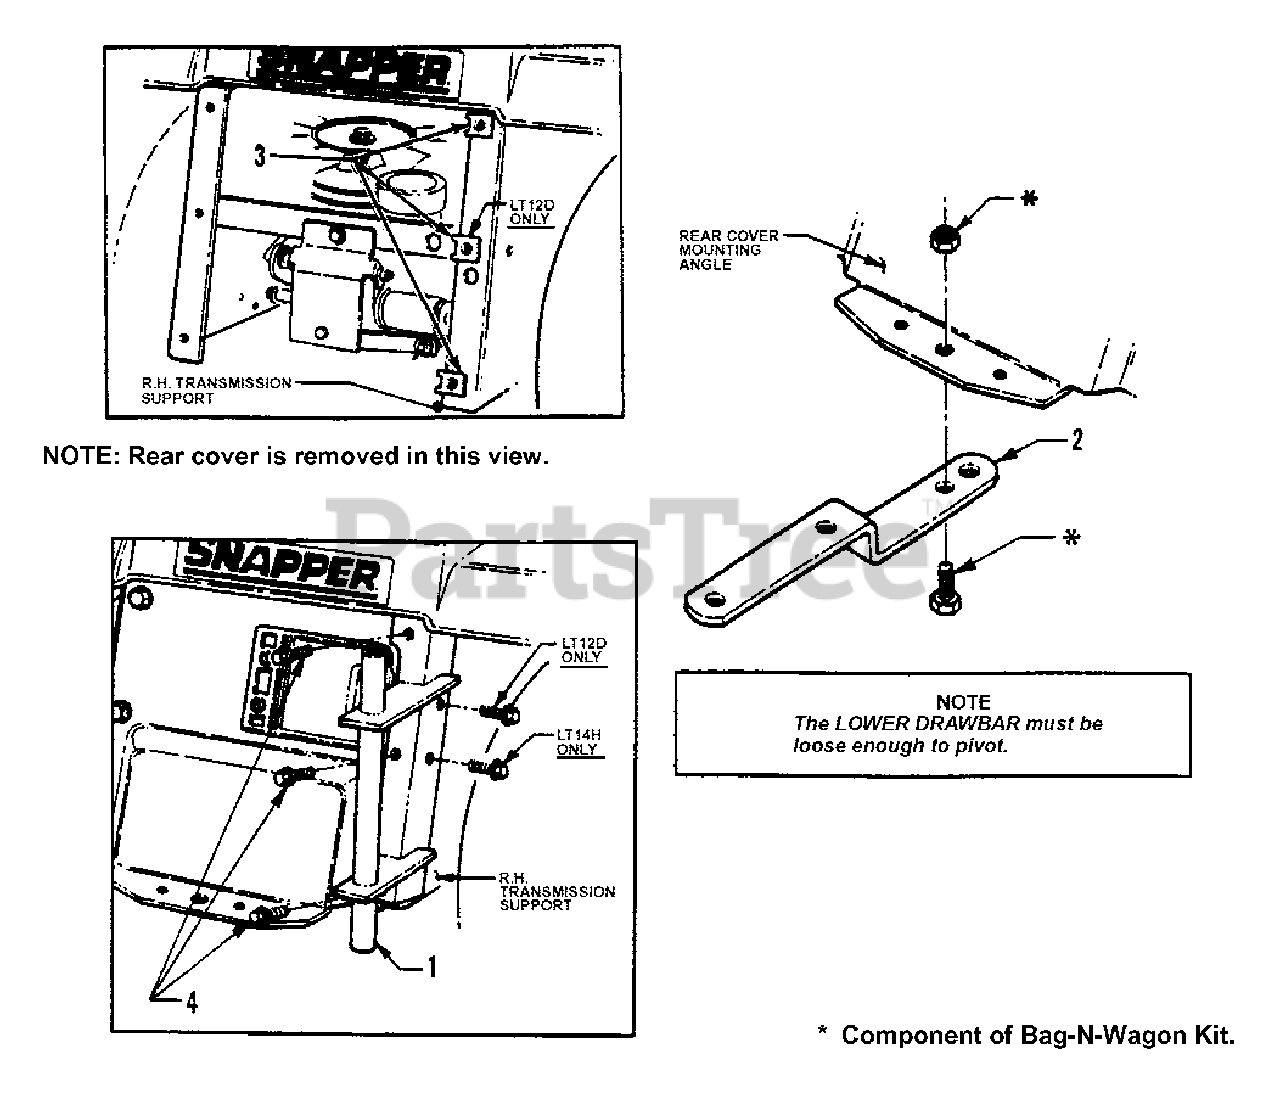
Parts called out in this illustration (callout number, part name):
1	WELDMENT, Adapter
2	DRAWBAR, Lower
3	NUT, 5/16" Push-on
4	SCREW, 5/16-18 x 3/4" Hex Washer Self-Tap
